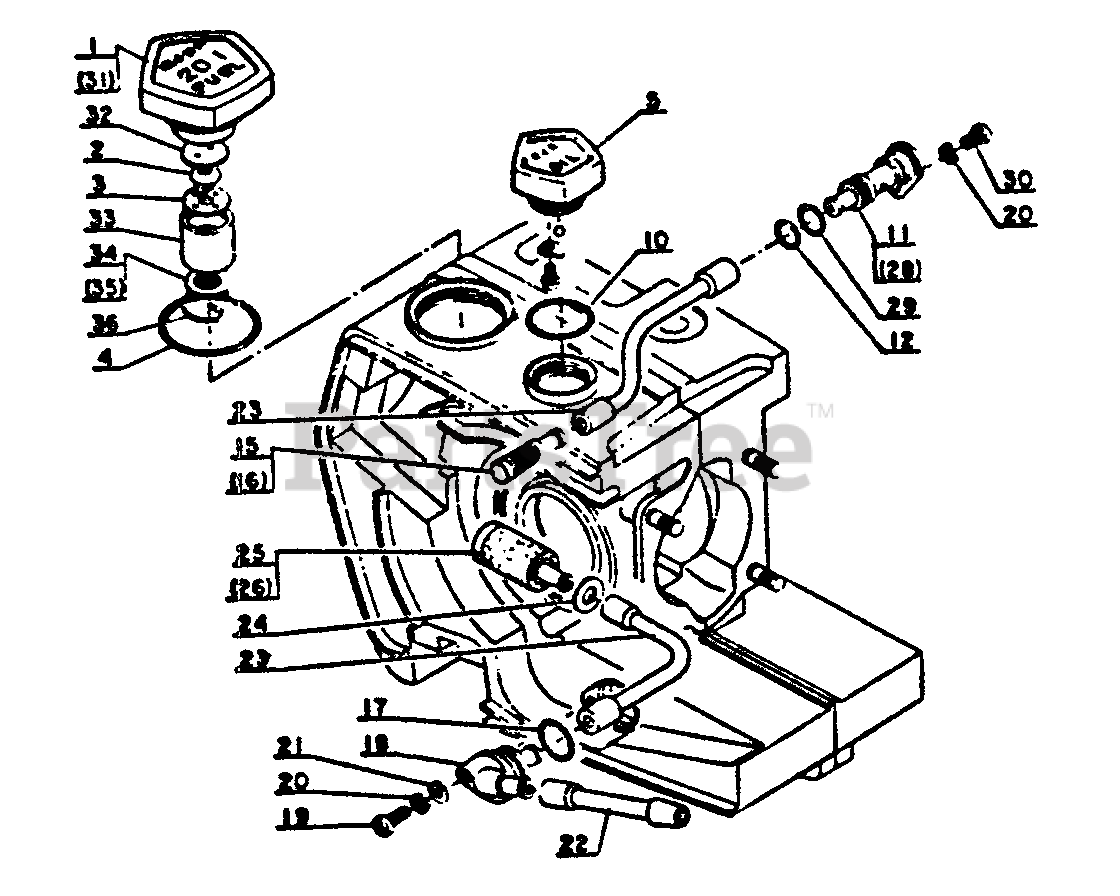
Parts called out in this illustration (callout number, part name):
1	CAP
2	VALVE, CHECK
3	HOLDER, VENT
5	CAP, OIL TANK
10	GASKET, CAP
11	CONNECTOR, PIPE
12	O-RING
15	FILTER, OIL
17	O-RING
18	CONNECTOR, PIPE
19	SCREW 4×14
20	WASHER, SPRING 4 MM
21	WASHER 4 MM
22	PIPE, FUEL - OUTER
23	PIPE
24	WASHER 6.5×11.5×0.8
25	FILTER, FUEL
29	O-RING
30	SCREW 4×10
34	FILTER, FUEL
36	RING, RETAINING
